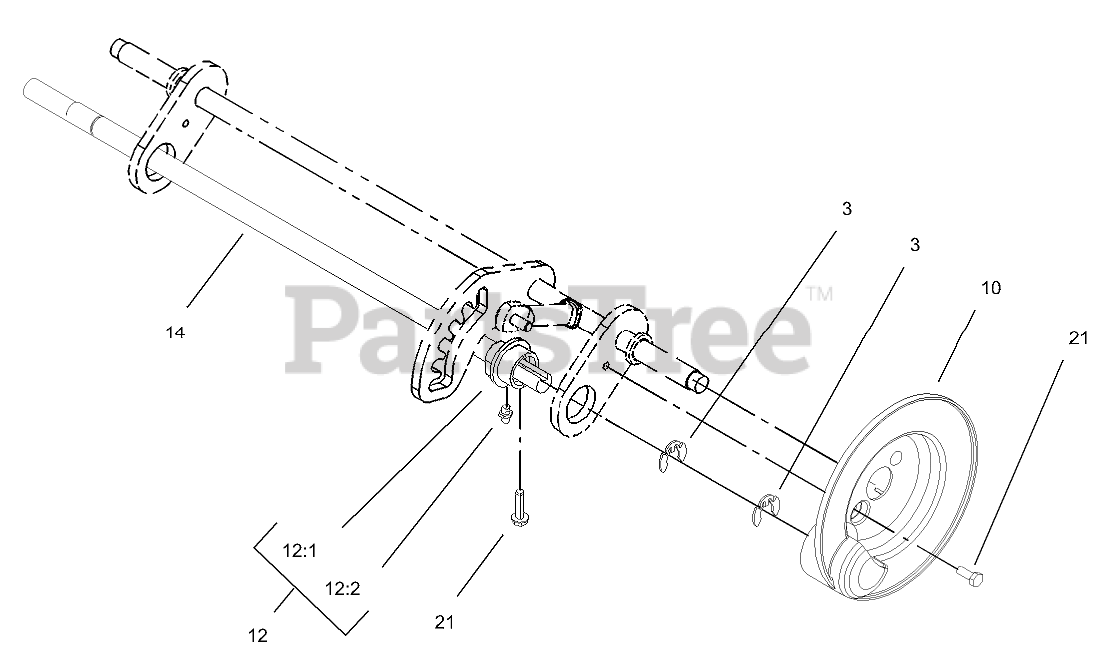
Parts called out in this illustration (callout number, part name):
3	RING-CLIP, LOCKING
10	COVER-GEAR
12	BUSHING ASM
12:1	BUSHING
12:2	FITTING-GREASE
14	SHAFT-PIVOT
21	SCREW-TAPTITE
